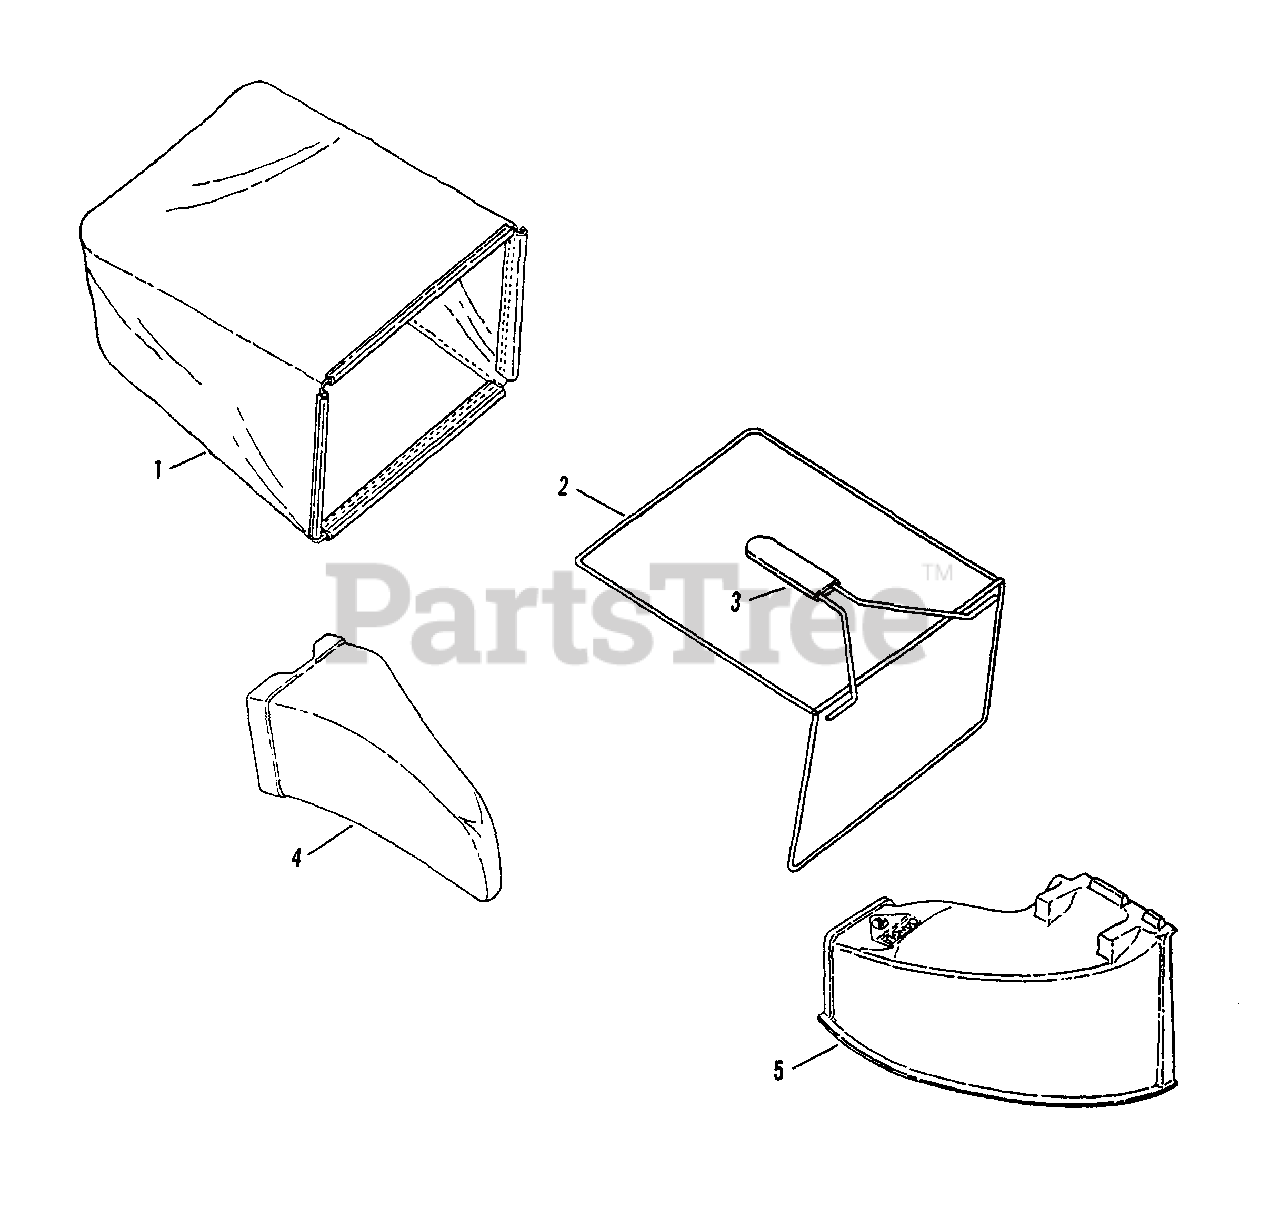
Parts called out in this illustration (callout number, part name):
1	GRASSBAG, Snapper Platinum Series
2	ASSEMBLY, Catcher Frame
3	GRIP, Catcher Frame
4	PLUG, Mulching
5	CHUTE, Side Discharge
